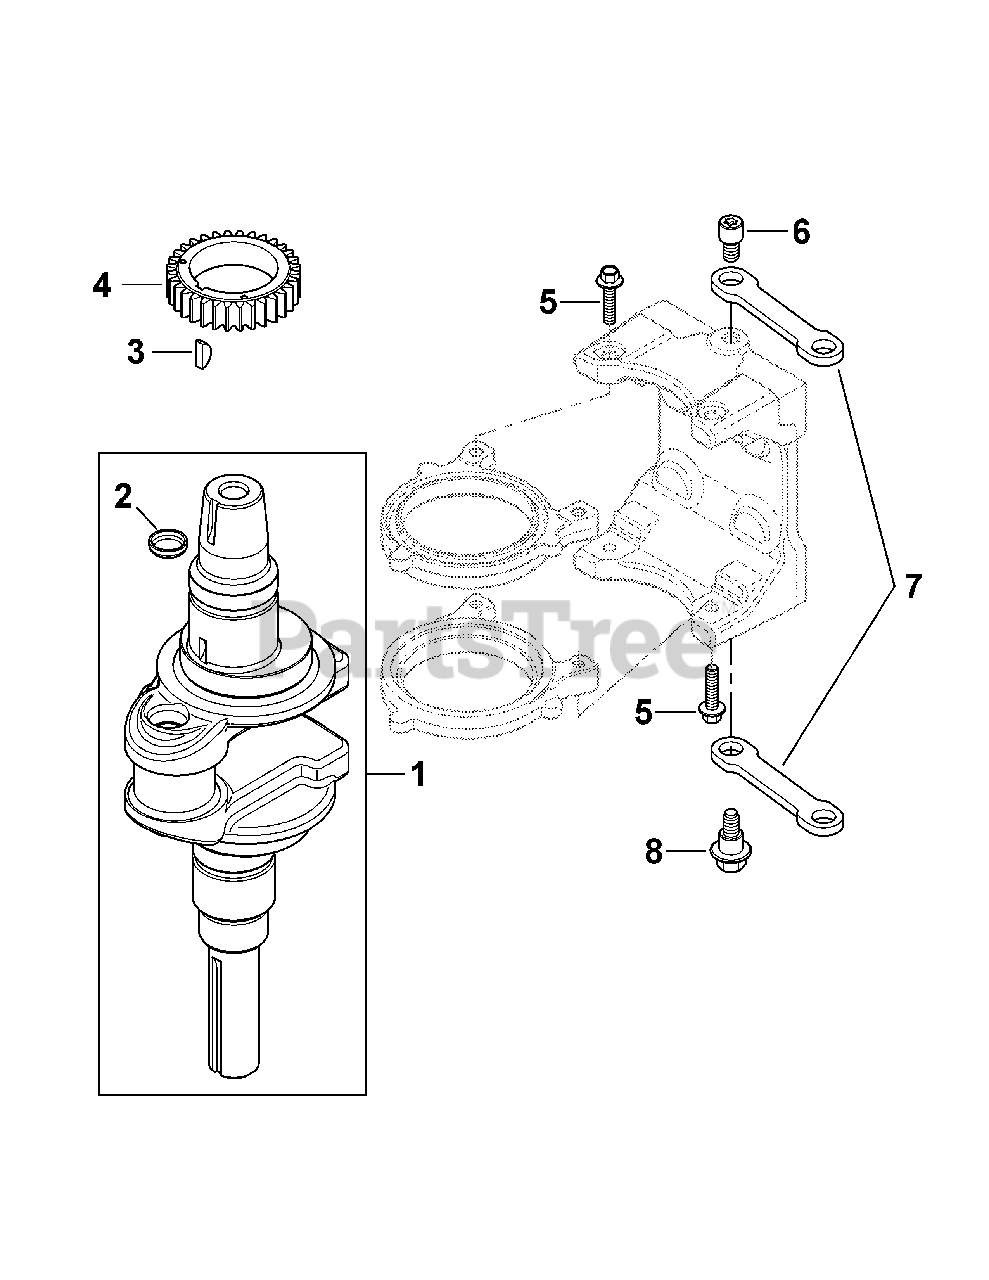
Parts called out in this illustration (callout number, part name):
1	Crankshaft Assembly Kit
3	Key, 3.16 X 5.8
4	Crankshaft Gear
5	Flange Screw, M6 X 1.0 X 25
6	Link Pivot Screw
7	Balance Weight Linkage
8	Shoulder Screw
9	Fuse Block
10	Fuse Block
11	Fuse Block
12	Fuse Block
13	Fuse Block
